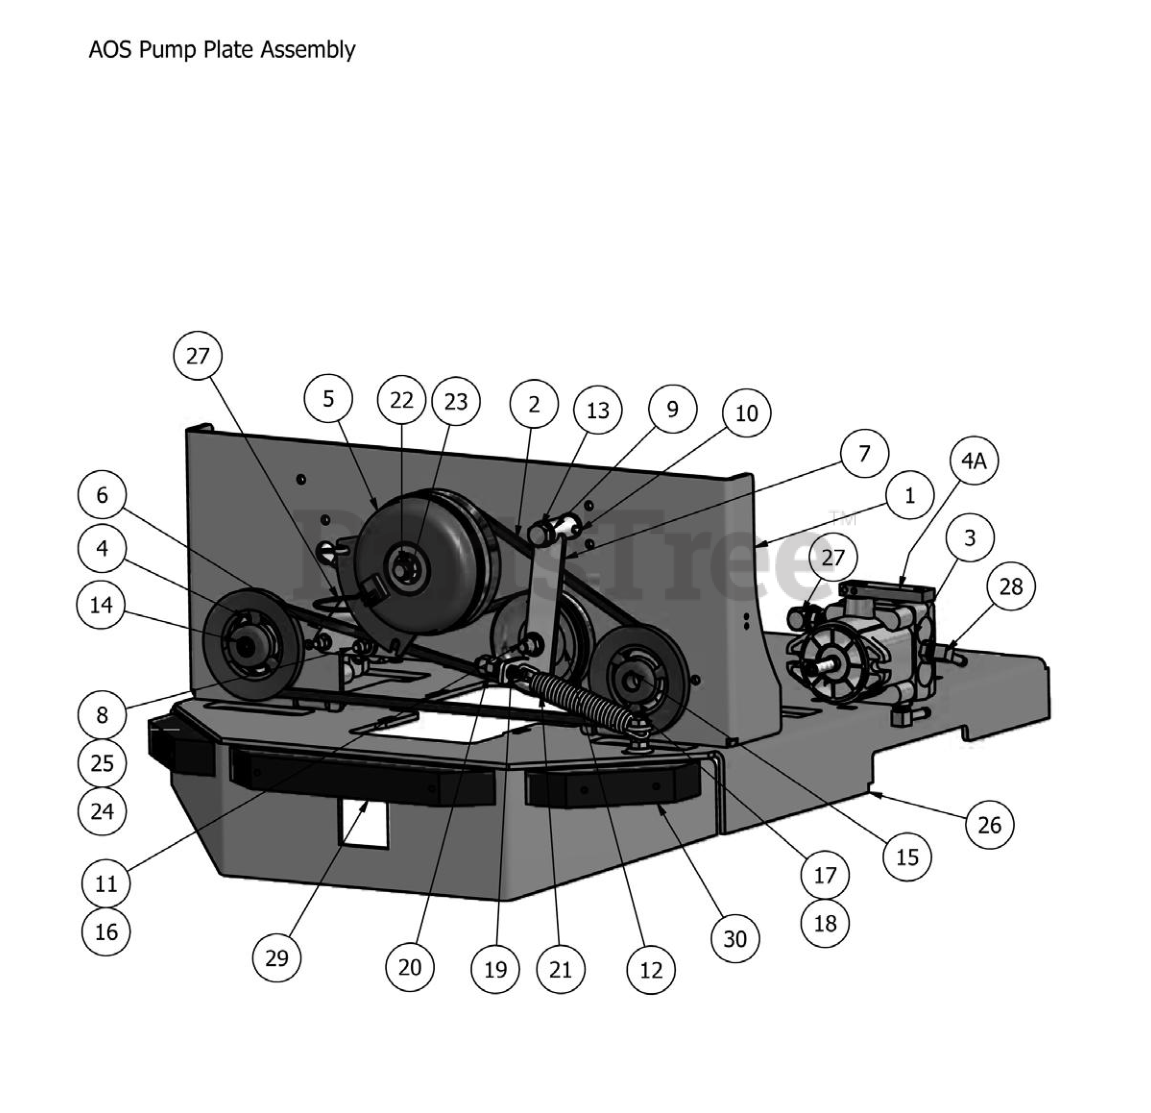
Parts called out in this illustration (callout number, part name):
1	Pump Mounting Plate AOS
3	Hydraulic Pump Right
4	Hydraulic Pump Left
6	PTO Engager Holder
7	Pump Idler Bracket
8	3/8" x 1 1/2" Hex Bolt
9	5/8 Nylon Washer
10	Grease Fitting (Drive-In Type)
11	1/2" x 2" Hex Bolt
12	4 3/4" Idler Pulley
13	5/8" x 4" Hex Bolt
14	5" Pump Pulley
15	5mm x 1.25" Key
16	1/2" Flange Nut
17	1/2 x 2" Carriage Bolt
18	1/2-13 Nylon Flange Nut
19	1/2-13 x 2-1/2 All Thd Stud
20	1/2" Hex Nut
21	6" Pump Idler Spring
22	7/16" x 2 1/2" Hex Bolt
23	7/16" Lock Washer
24	3/8" Lock Washer
25	3/8" Hex Nut
27	Hydraulic Fitting
27	Clutch Pigtail
28	3/8" x 9/16"-18 Male Fitting
29	14" Rubber Bumper
30	8" Rubber Bumper
